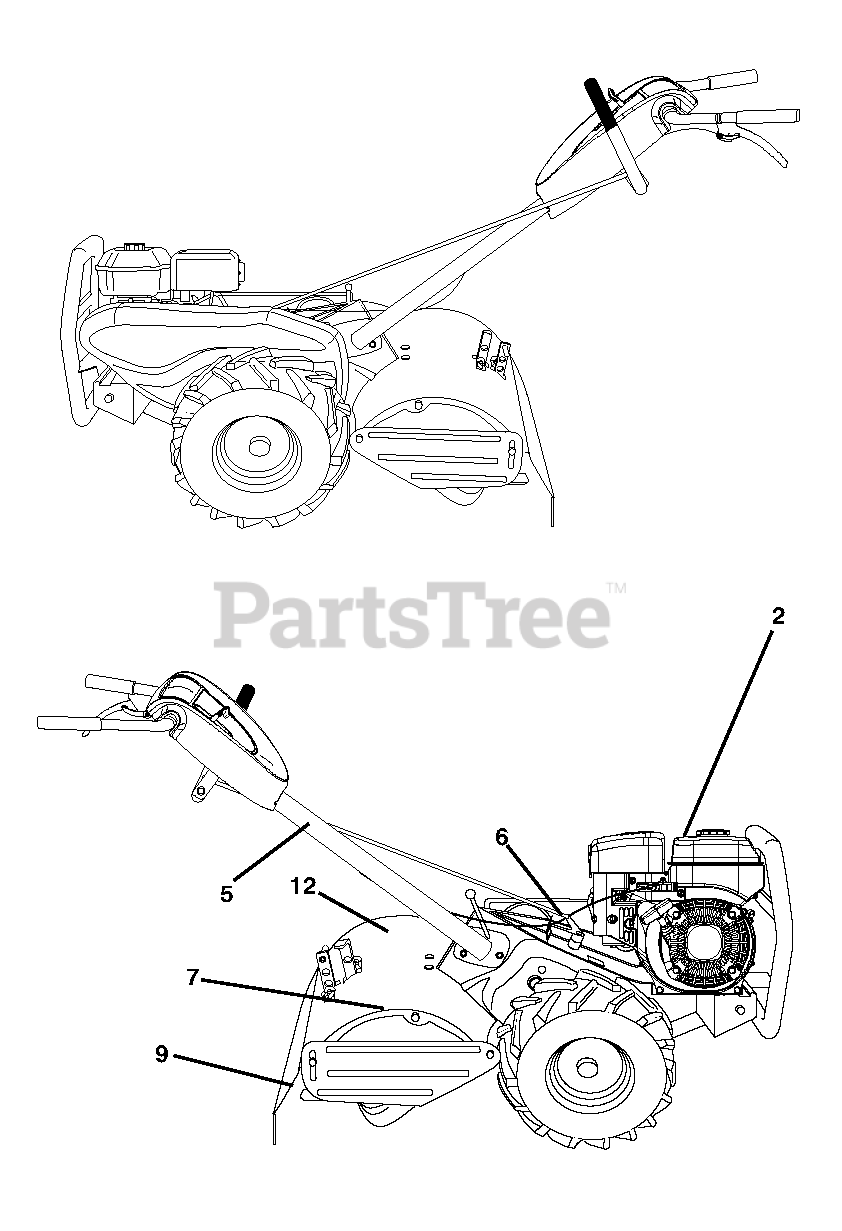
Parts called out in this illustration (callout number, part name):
2	DECAL.ETHANOL.E85 WARNING SYMB
5	DECAL TI (2 2)
6	DECAL.SHIFT.INDICATOR.DRT
7	DECAL.REVERSE.HUSQ.TILLER
9	DECAL.DRT.WARN.ENG/F
12	DECAL.FOWARD.HUSQ.TILLER
